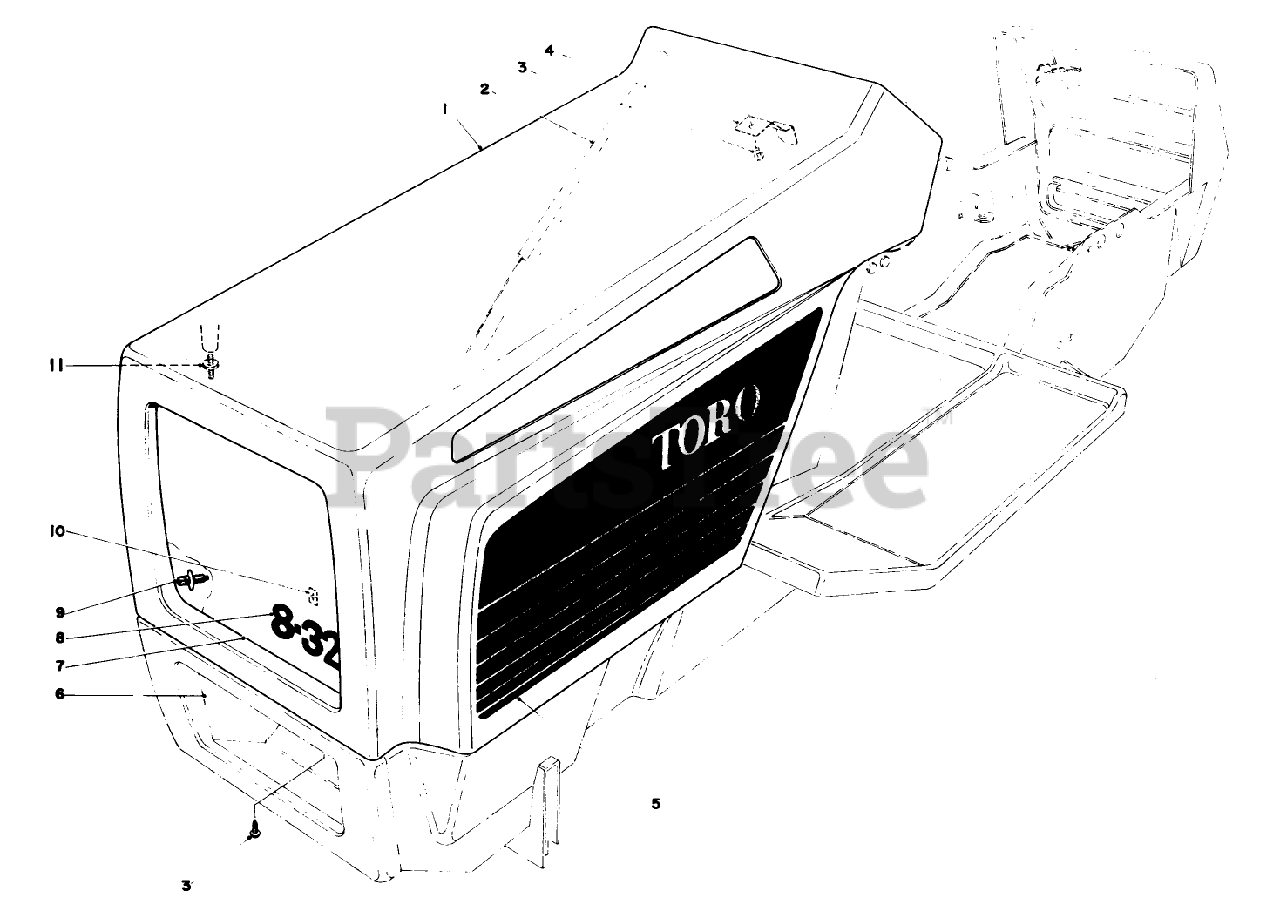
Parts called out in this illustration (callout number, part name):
3	SCREW-HWHTF
4	SPRING LATCH
5	Decal Hood LH.
6	LOWER GRILLE
